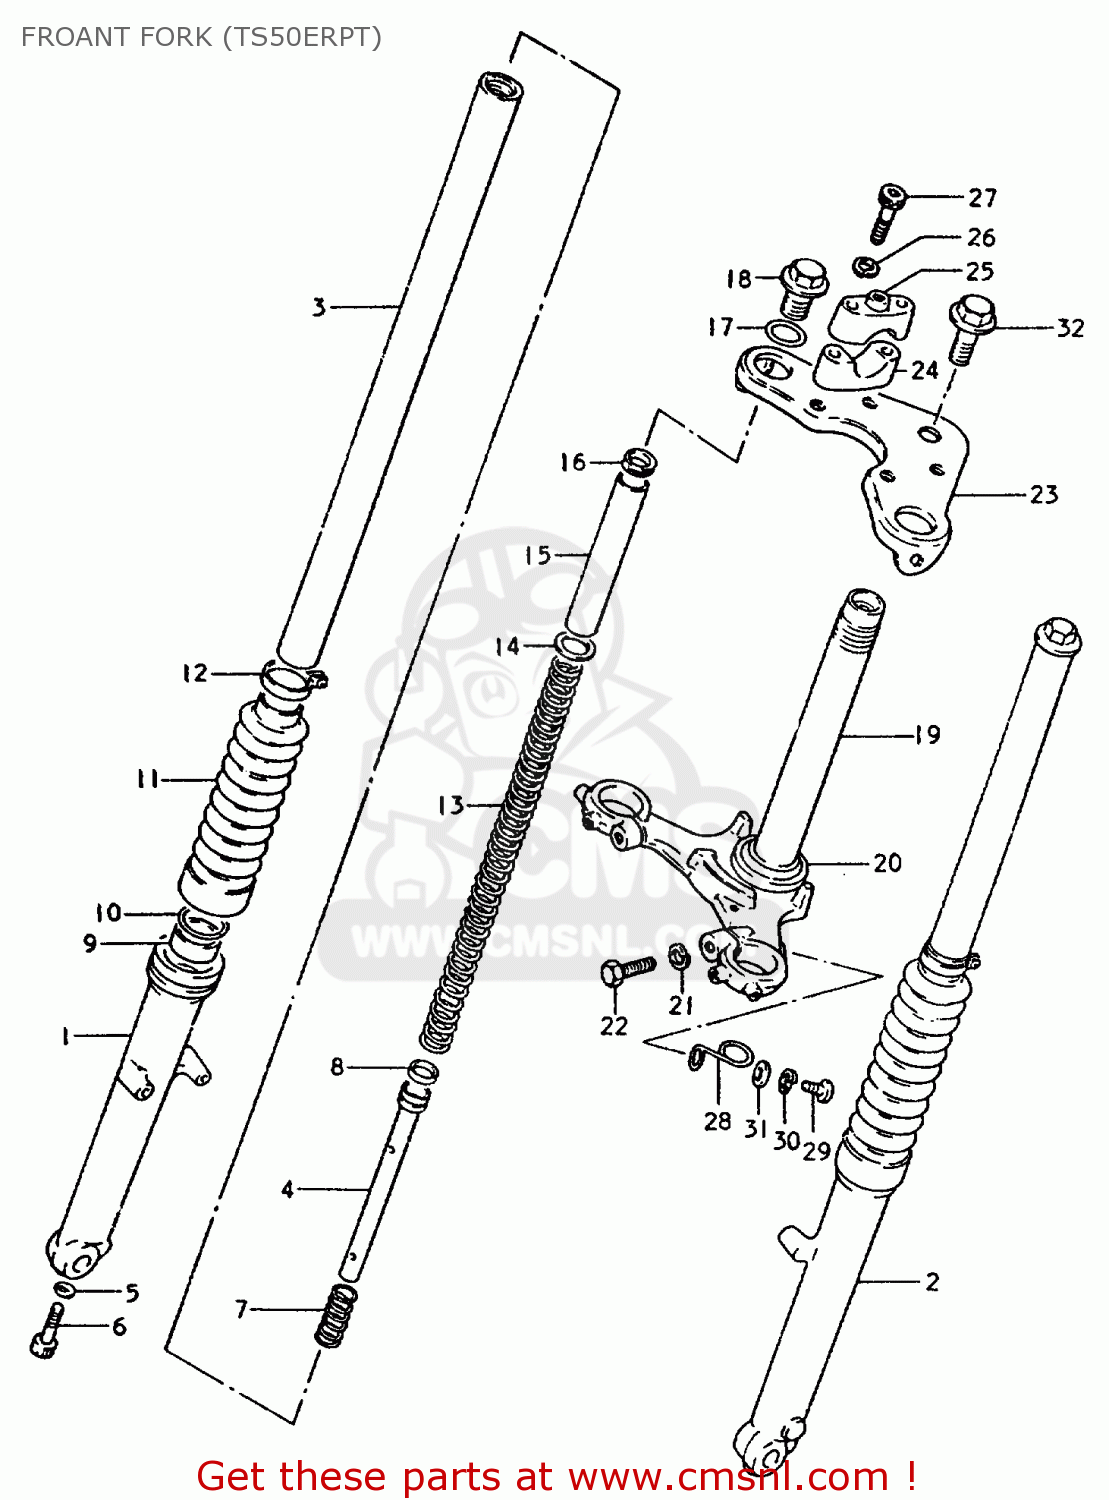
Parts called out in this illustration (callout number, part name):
1	TUBE, OUTER RH
2	TUBE, OUTER LH
3	TUBE, INNER
4	PIPE, SEAT
5	GASKET (NAS)
6	BOLT(8X27)
7	SPRING,REBOUND
8	RING,PISTON
9	OIL SEAL,FRONT FORK
10	RING,OIL SEAL STOPPER
11	BOOT
12	BAND
13	SPRING
14	JOINT,SPRING
15	SPACER,SPRING
16	NUT,FORK SPRING,UPPER
17	O-RING,FORK INNER TUBE
18	CAP
19	STEM, STEERING
20	RACE,STEERING OUTER LWR
21	LOCK WASHER
22	BOLT 10X30
23	STEM HEAD, STEERING
24	HOLDER,HANDLE UPR
25	HOLDER,HANDLEBAR
26	LOCK WASHER
27	BOLT
28	CLIP
29	SCREW 6X12
30	LOCK WASHER
31	WASHER
32	BOLT
